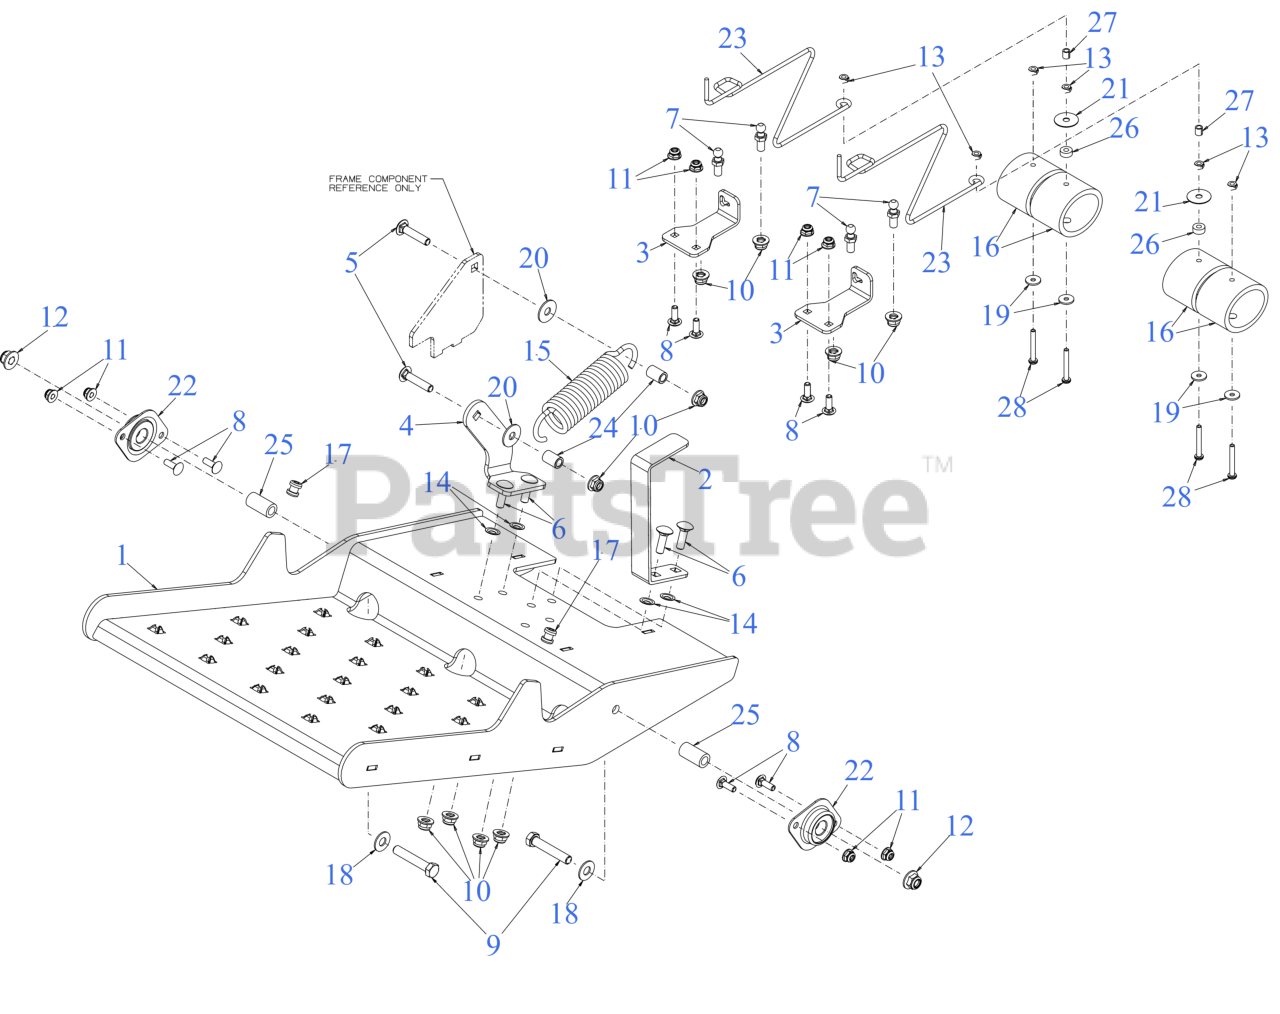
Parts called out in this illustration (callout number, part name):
1	PLATFORM
2	SWITCH BRACKET
3	ADJUSTMENT BRACKET
4	SPRING MOUNT BRACKET
5	CARRIAGE BOLT 5/16-18 x 1.50
6	CARRIAGE BOLT 5/16-18 x 1.00
7	BALL STUD 5/16-18
8	SCREW 1/4-20 x .75 GR5
9	SCREW 3/8-16 x 2.0 GR 8
10	FLANGE LOCK NUT 5/16-18
11	FLANGE LOCK NUT
13	LOCK NUT 10-24
15	EXTENSION SPRING 1.478 x 5.729
16	RADIAL BUMPER
18	FLAT WASHER
19	FLAT WASHER .192X.625X.057
20	FLAT WASHER 344X1.00
21	FLAT WASHER
22	BALL BEARING
23	ADJUSTMENT SUPPORT ROD
24	SLEEVE .33X.50X.75 LG
25	SPACER .380x.624x1.040
27	SPACER-SPLIT
